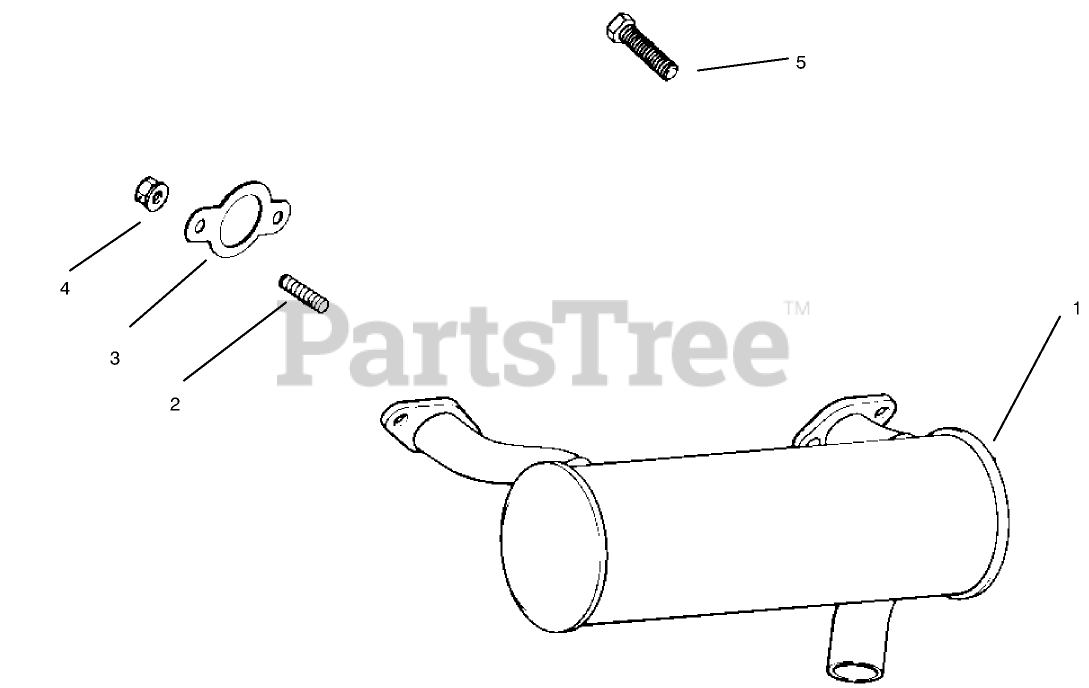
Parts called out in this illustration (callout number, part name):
1	Muffler
2	Stud-Muffler
3	Gasket-Exhaust
